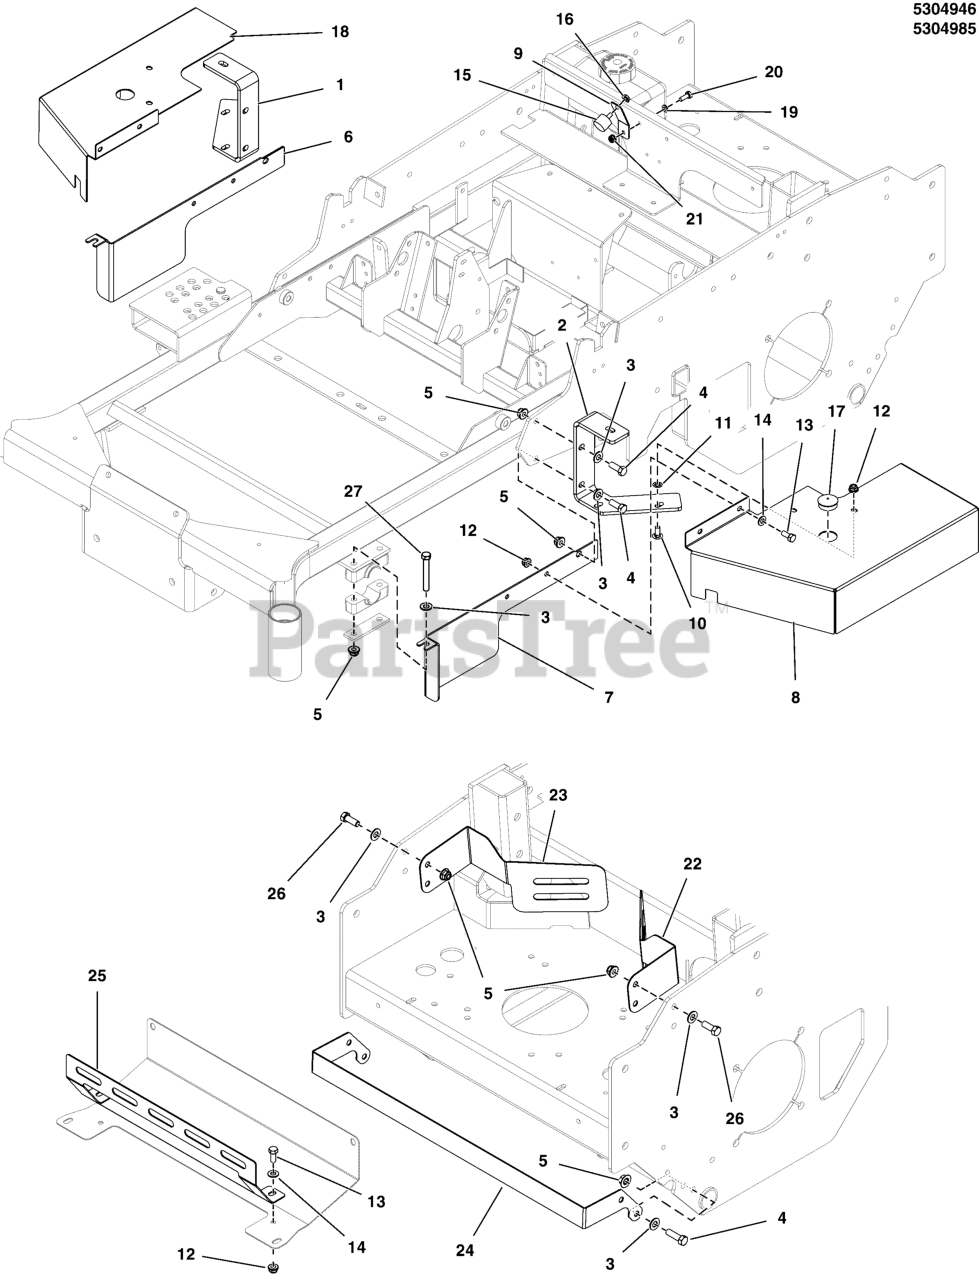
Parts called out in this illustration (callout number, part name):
1	BRACKET, TANK MOUNT, RH - RED
2	BRACKET, TANK MOUNT, LH - RED
3	WASHER, 3/8 SAE
4	BOLT, 3/8-16 X 1-1/4" GD5 CZ
5	NUT, 3/8-16 HEX NYLOCK FLANGE
6	PLATE, GUARD MOUNT, RH - RED
7	PLATE, GUARD MOUNT, LH - RED
8	PLATE, DECK GUARD, LH - RED
9	TAB, SEAT LOCK BRACKET - BLK
10	BOLT, 5/16-18 X 3/4, CARRIAGE, GD5, CZ
11	5/16 PUSH-ON NUT RETAINER, STL, CZ
12	NUT, 5/16-18 HEX NYLOCK FLANGE
13	BOLT, 5/16-18 X 3/4 GD5
14	WASHER, 5/16" SAE
15	BUMPER, RUBBER 1/4-20
16	NUT, 1/4-20 HEX SERR. FLANGE
17	PLUG, PANEL, 1.25 BLACK
18	PLATE, DECK GUARD, RH
19	WASHER, 1/4 SAE
20	BOLT, 1/4-20, GD5 CZ
21	NUT, 1/4-20 HEX NYLOCK FLANGE
22	PLATE, FAN GUARD, RH - RED
23	PLATE, FAN GUARD, LH - RED
24	PLATE, CLUTCH GUARD, REAR - RED
25	PLATE, MUFFLER SHIELD, CE - BLK
26	BOLT, 3/8-16 X 1" GD5 CZ
27	BOLT, 3/8-16 X 2-3/4" GD5 CZ
